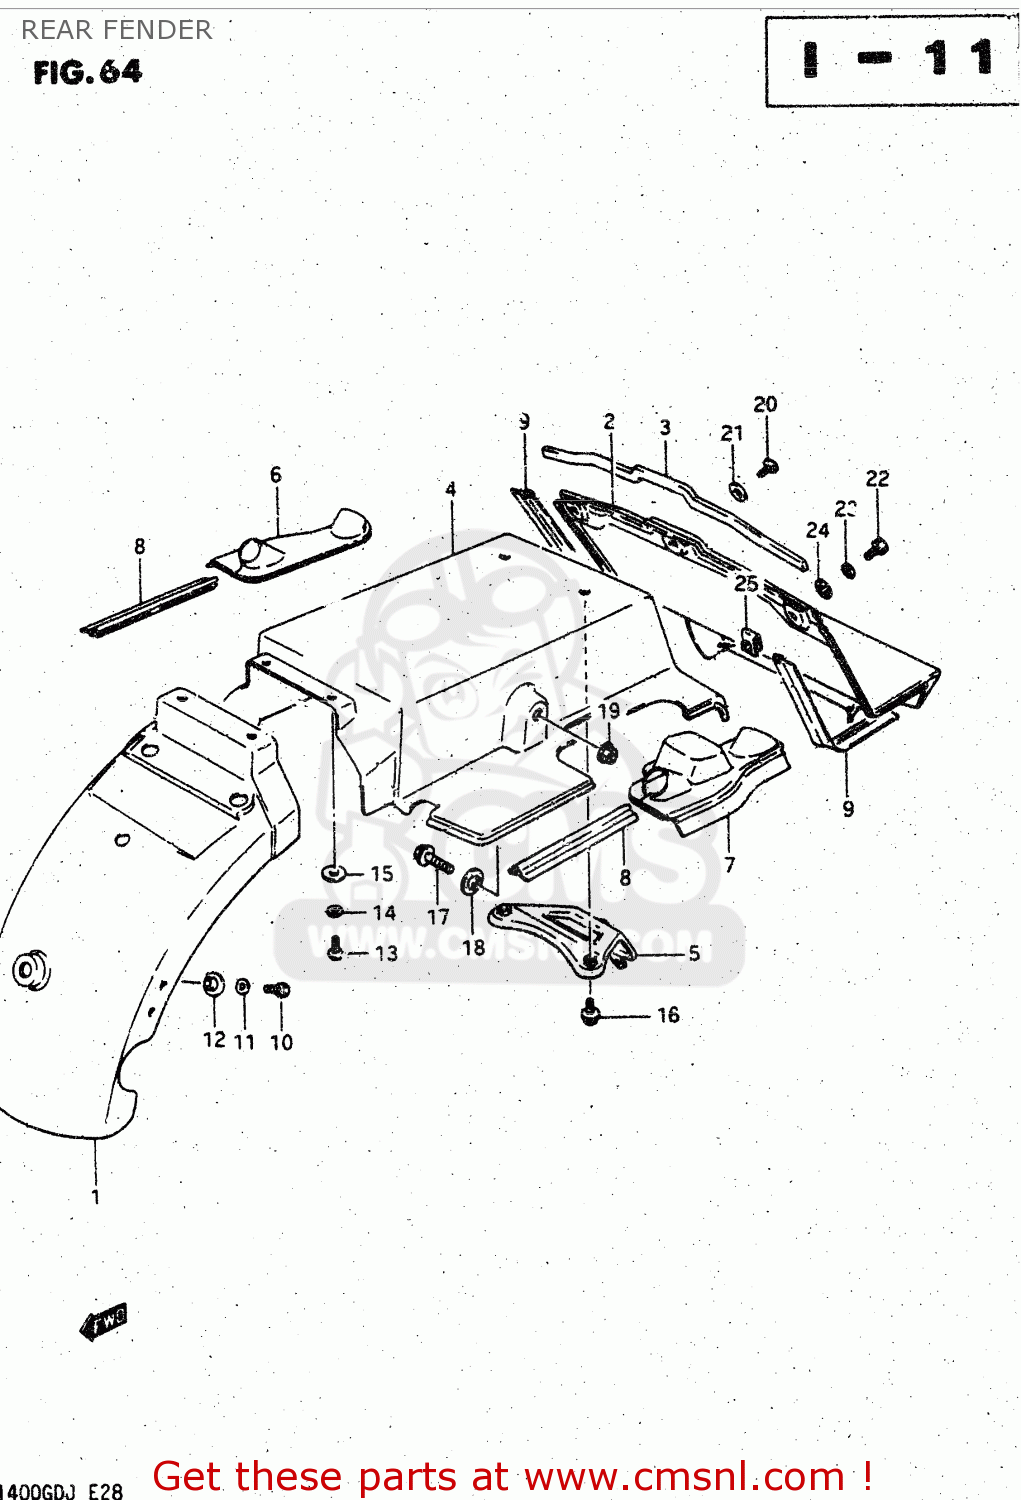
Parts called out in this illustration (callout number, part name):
1	BODY,REAR FENDER,FRONT
2	FENDER,REAR
3	SEAL,REAR FENDER,REAR
4	BODY,REAR FENDER,CENTER
5	REINFORCEMENT COMP,REAR FENDER
6	COVER,REAR FENDER
7	COVER,REAR FENDER SIDE,LEFT
8	WEATHER STRIP, CENTER
9	WEATHER STRIP, REAR
10	BOLT
11	WASHER,LOCK
12	WASHER
13	SCREW
14	WASHER,LOCK
15	WASHER
16	BOLT
17	BOLT 8X30
18	WASHER
19	NUT
20	SCREW
21	WASHER (5.5X14X1.2)
22	BOLT
23	WASHER,LOCK
24	WASHER
25	NUT
